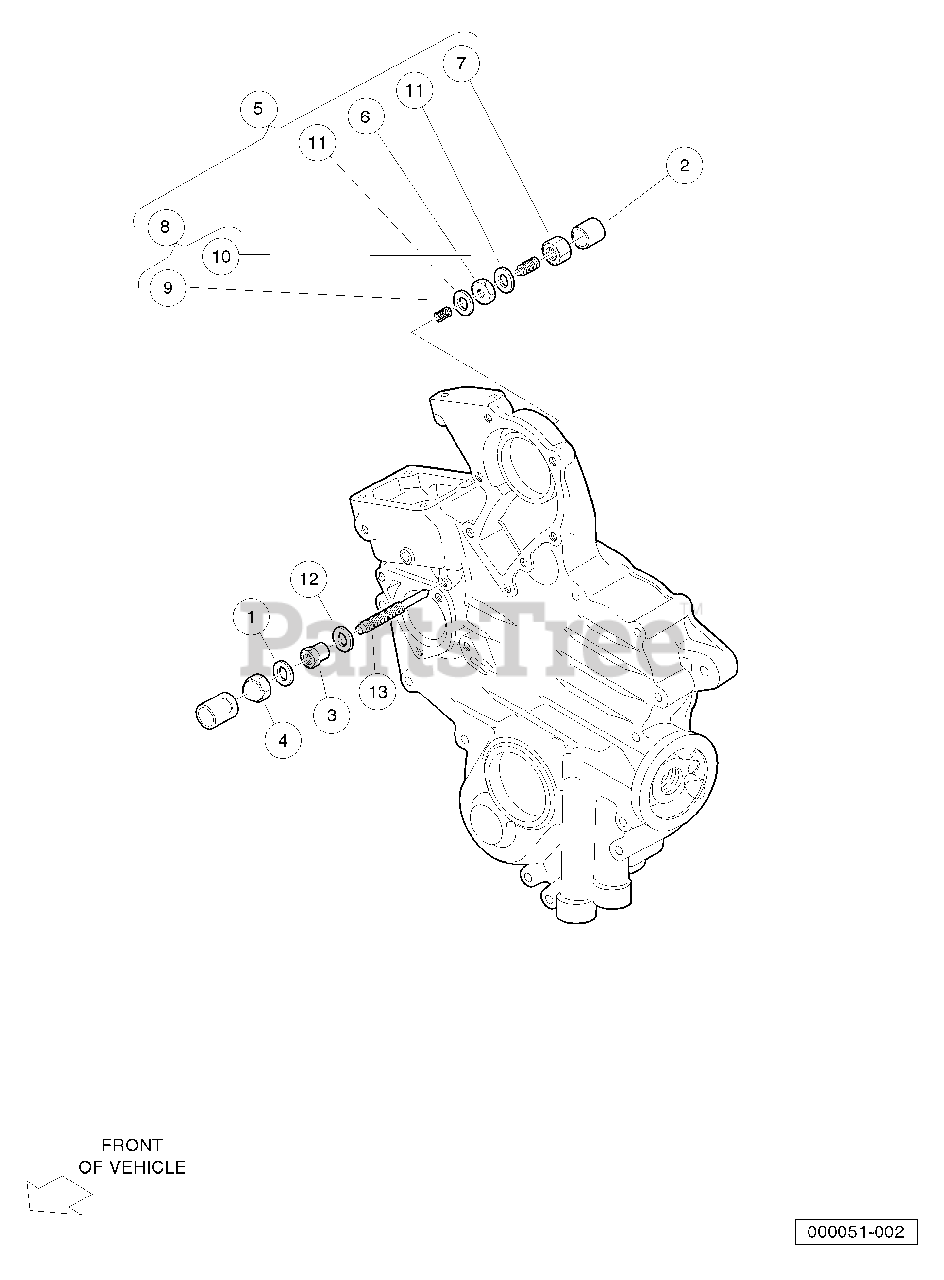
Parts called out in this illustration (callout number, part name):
1	Gasket, 6 X 10
2	Cap, Bolt Assy
3	Nut, Lock, Special
4	Nut, Special
5	Assy, Idle Apparatus
6	Nut, M8, D722 Idle App, Specl
7	Nut, M8, D722 Idle App
8	Assy, Bolt, Adjusting
9	Spring, Idle Apparatus
10	Stud, Idle Adjustment
11	Gasket, Idle Apparatus, Rear
12	Gasket, Idle Apparatus, Front
13	Bolt, Idle Adjusting
